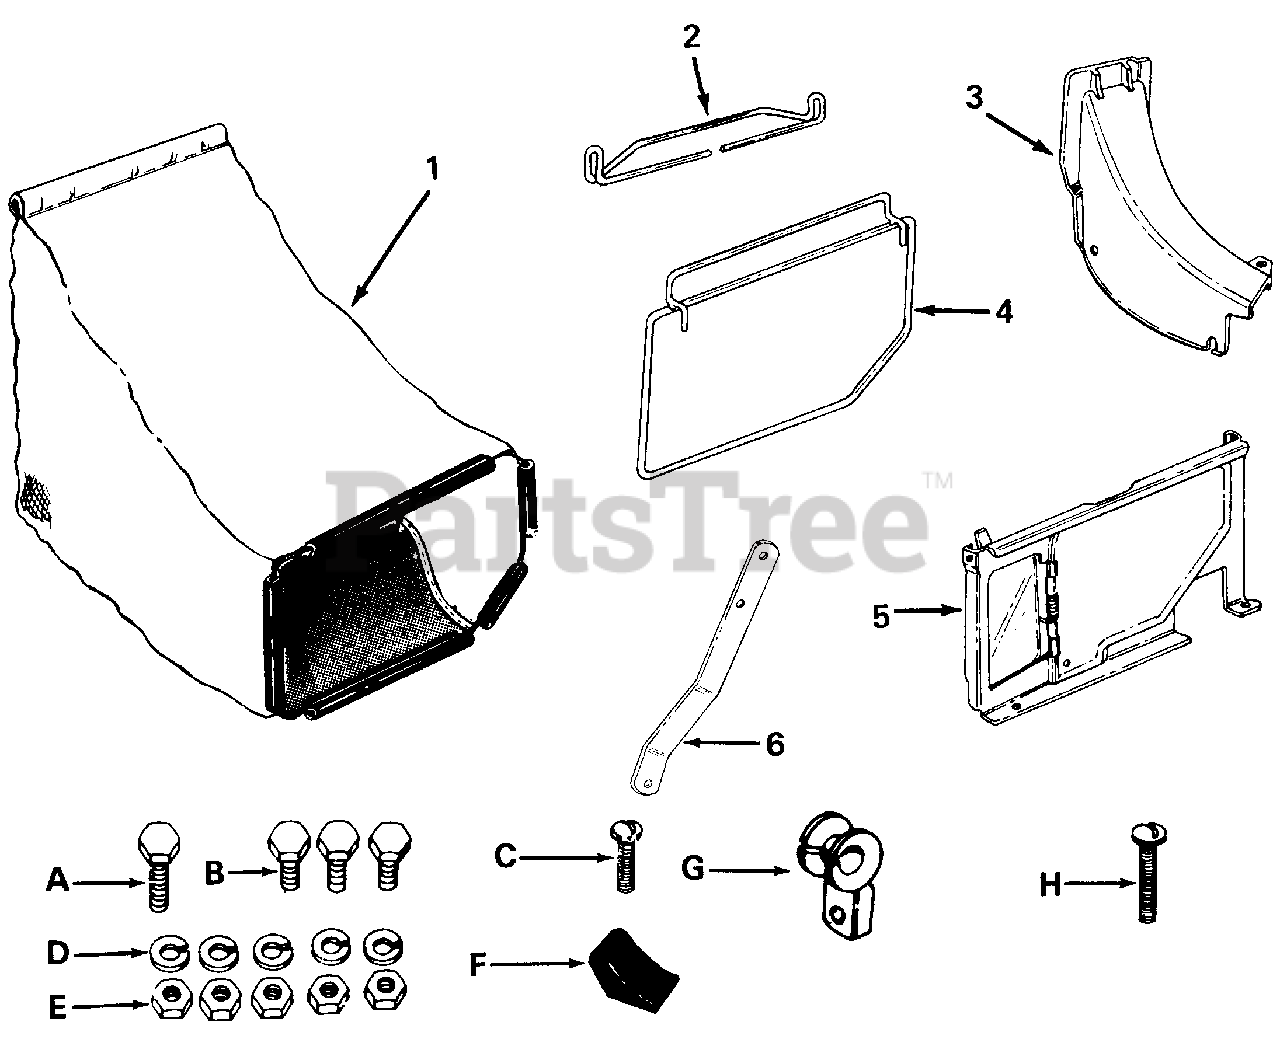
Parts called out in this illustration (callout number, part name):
1	Grass Bag
2	Grass Catcher Handle
3	Top Discharge Chute
4	Front Catcher Frame
5	Top Catcher Panel
6	Panel Support Bracket
A	Hex Bolt 1/4-20 x 518" Lg.*
B	Hex Bolt 1/4-20 x 1/2" Lg.*
C	Truss Machine Screw 1/4-20 x 1/2" Lg.*
D	Lock Washer 1/4" I.D.*
E	Hex Nut 1/4-20 Thread*
F	Door Grip
G	Rope Guide
H	Truss Machine Screw 1/4-20 x 1.0" Lg.*
